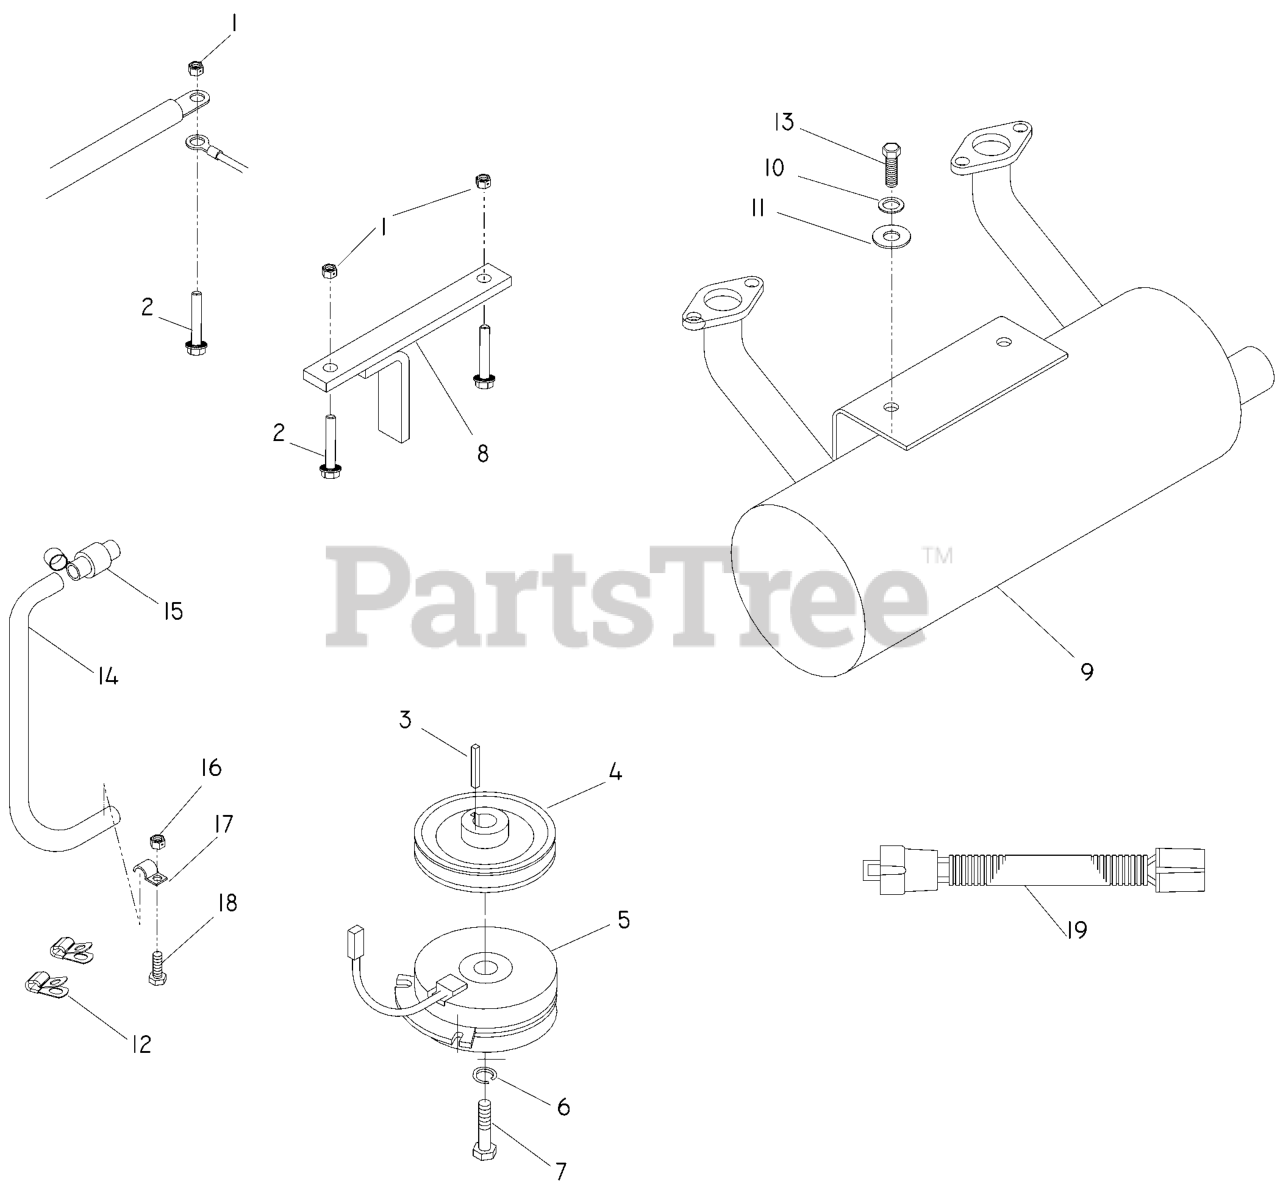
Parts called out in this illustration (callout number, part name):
1	NUT 5/16C CENTERLOCK
2	HCS 5/16-18 X 1-3/4 SERATED
3	KEY 1/4" SQ X 1 7/8"
5	ELECTRIC CLUTCH W/CABLE
6	WASHER 7/16 LOCK
7	BOLT 7/16F X 2 1/2
8	CLUTCH TIE DOWN
9	MUFFLER KOHLER GEN II
10	WASHER.LOCK.HVY.HLCL.SPR.5/16
11	WASHER 5/16 FLAT
12	DOUBLE TUBE CLAMP
13	HCS 5/16C X 3/4
14	OIL DRAIN HOSE
15	OIL DRAIN FITTING
16	NUT 1/4C CENTER LOCK
18	HCS 1/4C X 3/4 HCS
19	KOH PIGTAIL
